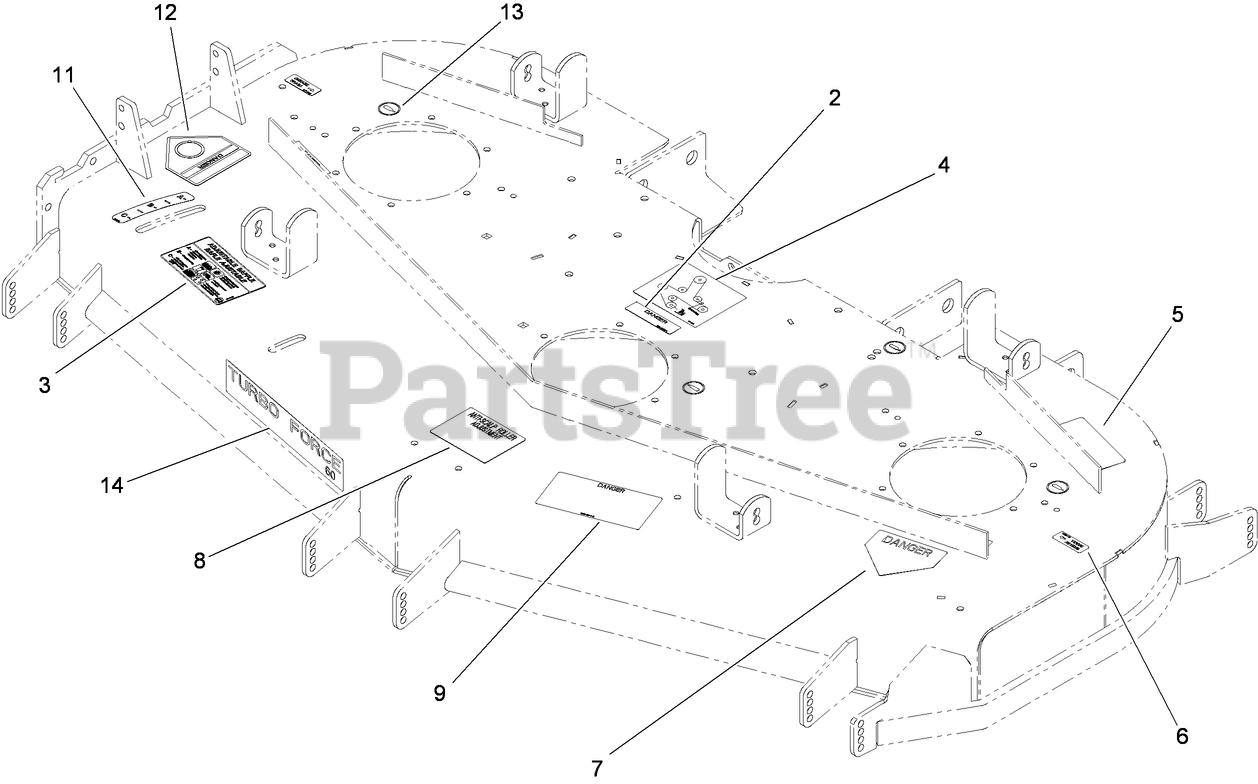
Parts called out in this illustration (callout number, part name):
2	DECAL-COVER, MISSING
3	DECAL-ADJUSTMENT, BAFFLE
4	DECAL-ROUTING, BELT
5	DECAL-TORQUE
6	Decal-Grease
7	DECAL-DANGER
8	DECAL-SCALP, ANTI
9	DECAL-DANGER, THROWN OBJECT
11	DECAL-SETTING, BAFFLE
12	DECAL-DANGER
13	DECAL-GREASE
